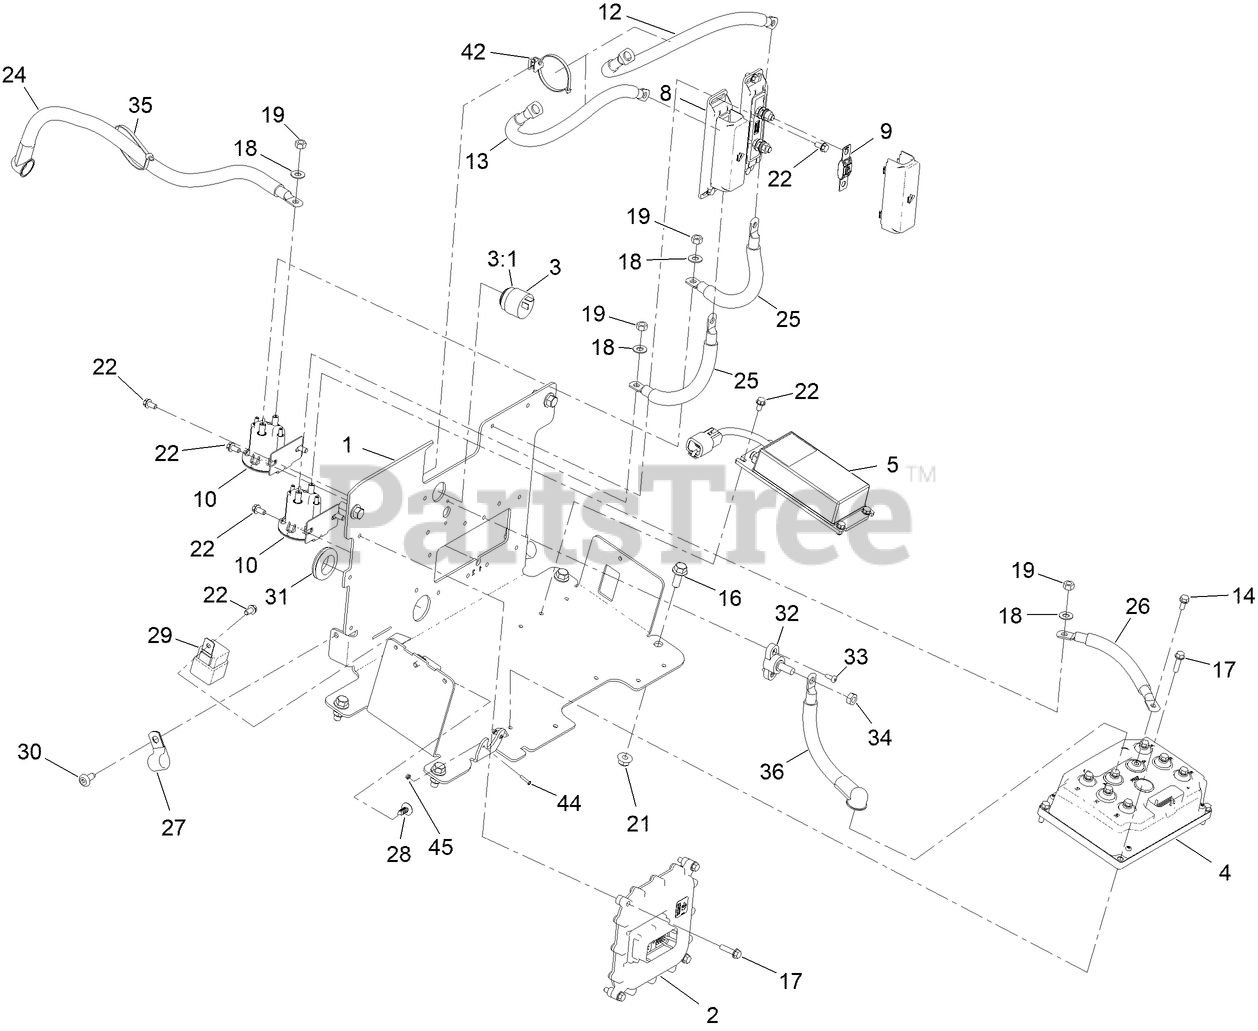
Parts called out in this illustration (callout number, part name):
1	PLATE-MNT, ELECTRICAL
2	CONTROLLER
3	AUDIO ALARM ASM
3:1	NUT-PLASTIC, KNURLED
4	INV/CTRLR-48V,DUAL 94Arms
5	CONVERTER DC-DC
8	HOLDER-FUSE
9	FUSE-200A
10	CONTACTOR-DC, 12V
12	CABLE-BATTERY, RD ASM
13	CABLE-BATTERY, RD ASM
14	SCREW-SEMS
16	SCREW-HHF
17	SCREW-HWHTF
18	WASHER
19	NUT-HEX
21	NUT-HF, NI
22	SCREW-HWH
24	CABLE-BATTERY, RD ASM
25	CABLE-BATTERY, RD ASM
26	CABLE-BATTERY, RD ASM
27	CLAMP-R
28	PLUG-PLASTIC
29	RELAY
31	GROMMET
32	BLOCK-JUNCTION
33	SCREW-FORMING, THREAD
34	NUT-HEX
35	TIE-CABLE
36	CABLE-BATTERY, BK ASM
42	CLIP-HARNESS. EDGE, W/TIE-WRAP
44	SCREW-PPH
45	NUT-HEX, NYL INS
